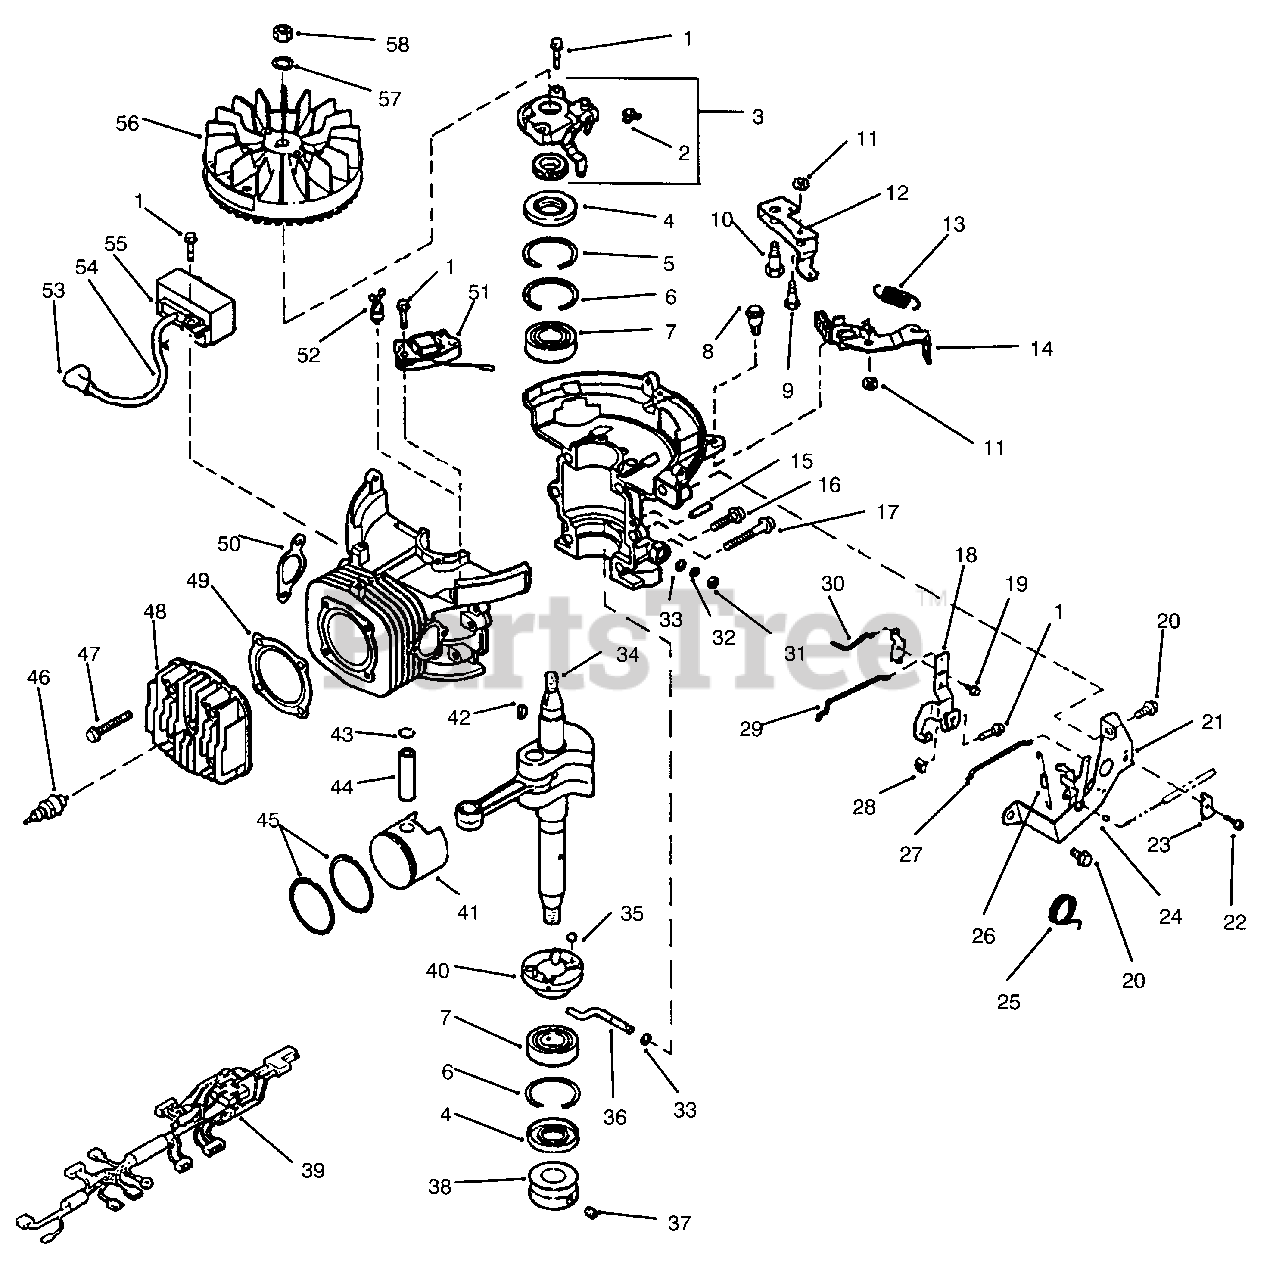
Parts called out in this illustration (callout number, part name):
2	Clamp-Oil Line
3	Oil Pump Kit w/Oil Lines (Incl. Ref. No. 2)
4	Oil Seal-Crankshaft
5	Ring-Retaining
6	Ring-Retaining
7	Bearing-Crankshaft
8	Shoulder Bolt
9	Shoulder Bolt
10	Shoulder Bolt
12	Brake Actuator
13	Brake Spring
14	Brake & Switch
15	Pin-Taper
18	Kit-Gov. & Oil Pump Lever (Incl. Ref. No.19)
21	Assy.-Governor Bracket (Incl. Ref. No. 25)
23	Clamp-Throttle Cable
24	Retainer-Throttle Wire
25	Spring-Torsion
26	Spring-Governor
27	Rod-Choke
29	Rod-Throttle
30	Rod-Oil Pump Control
31	Seal-Oil, Govenor Shaft
32	Ring-Retain .-Gov. Shaft
33	Washer-Governor Shaft
34	Crankshaft & Conn. Rod
35	Ball-Governor
36	Shaft-Governor
37	Screw-Set, Engine Pulley
38	Pulley-Engine
39	Wire Harness
40	Ramp-Governor
41	Assy.-Piston & Ring (Std.) (Incl. Ref. No. 43-45)
41	Assy.-Piston & Ring (0.020" Oversize) (Incl . Ref #43-45)
43	Ring-Retaining
44	Pin-Wrist
45	Ring Set (Standard)
45	Ring Set (0.020" Oversize)
46	Spark Plug
47	Screw-Cyl. Head to Block
48	Head-Cylinder
49	Gasket-Head
50	Gasket-Exhaust
51	Alternator
52	Wire Tie
53	Assy.-Cover & Terminal
54	High Tension Lead & Cover (Incl. Ref. No. 53)
55	Module-C.D. Ignition (Incl. Ref. No. 53-54)
56	Flywheel
57	Lockwasher
58	Nut-Flywheel
